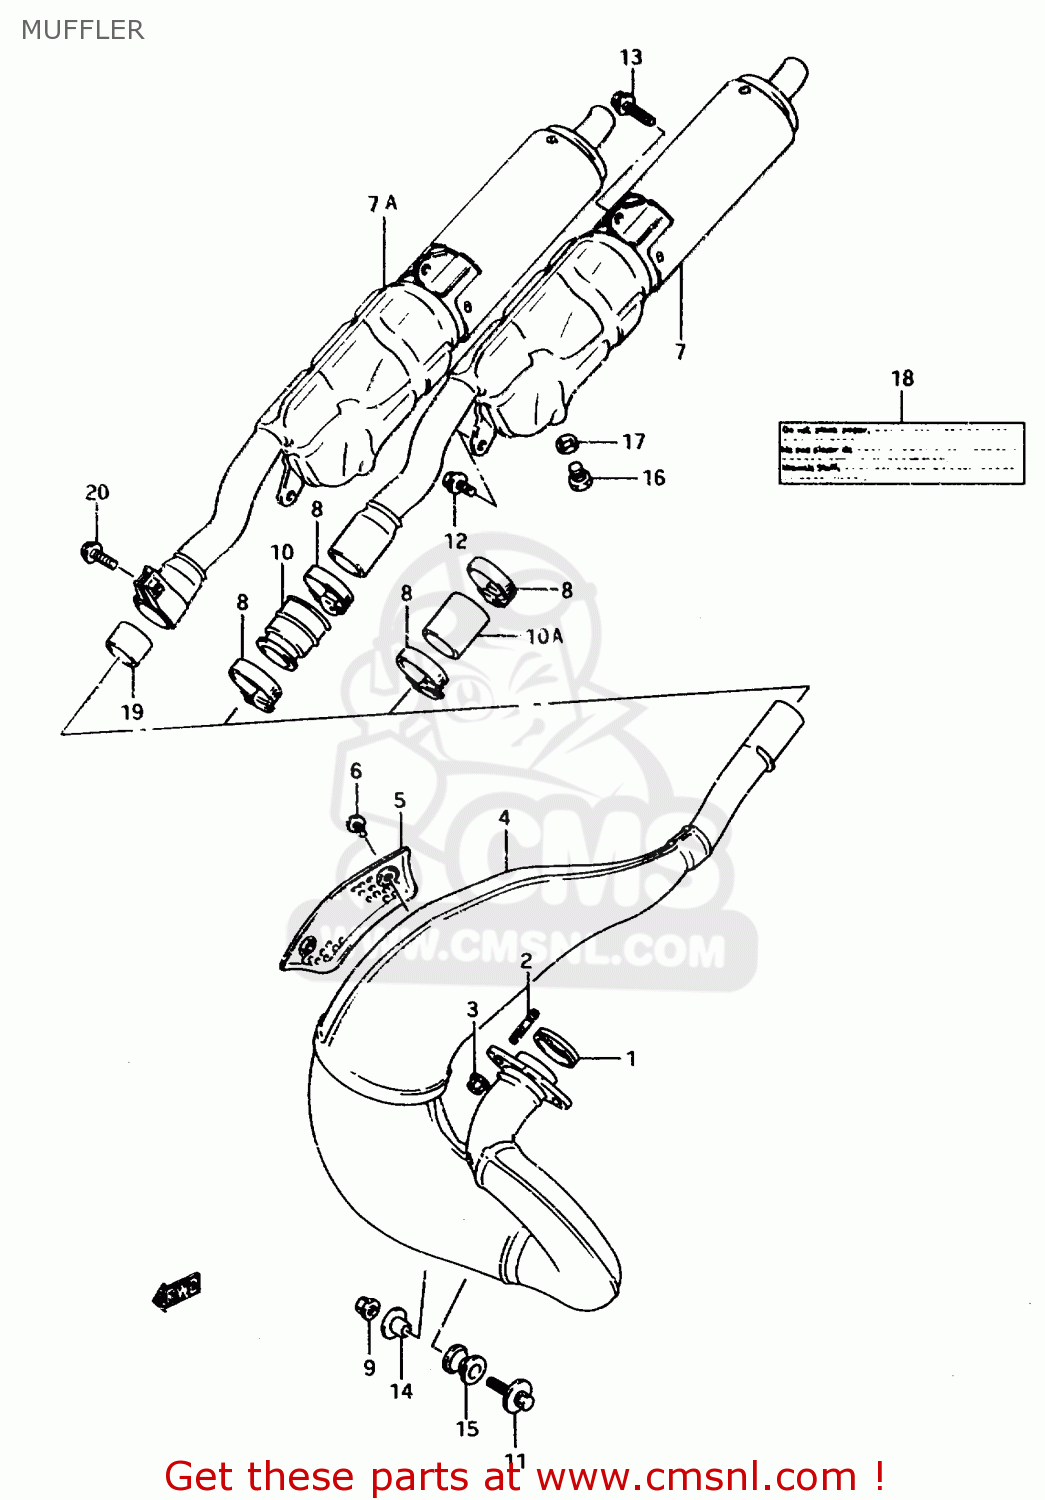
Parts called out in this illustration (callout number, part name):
1	GASKET,EXHAUST PIPE
2	STUD BOLT
3	NUT
4	BODY, MUFFLER,1ST
5	COVER, 1ST MUFFLER
6	SCREW
7	MUFFLER ASSY, 2ND
7A	MUFFLER ASSY, 2ND
8	CLAMP
9	NUT
10	CONNECTOR,2ND MUFFLER
10A	CONNECTOR, MUFFLER
11	BOLT 8X35
12	BOLT
13	BOLT(8X20)
14	SPACER(8.6X12X17.5)
15	CUSHION
16	PLUG(12X9)
17	GASKET(12.1X16.2X3.7) (NAS)
18	LABEL, MUFFLER CAUTION
19	GASKET,2ND MUFFLER (NAS)
20	BOLT
